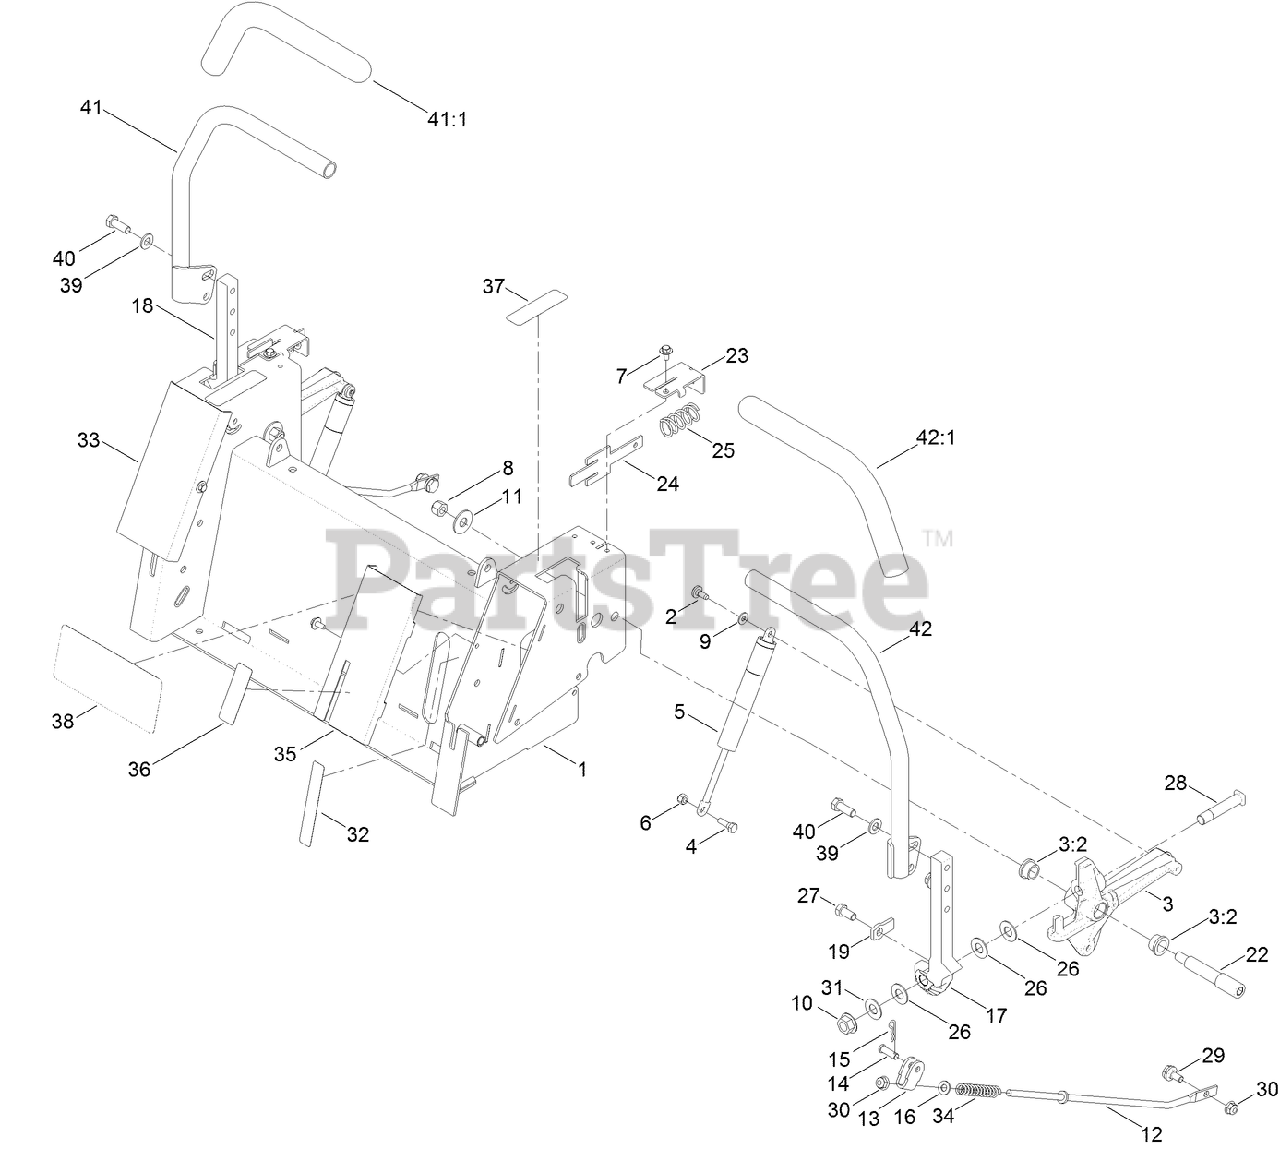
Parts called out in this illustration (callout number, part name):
1	BOX-CONTROL
2	SCREW-SHOULDER
3	ACTIVATOR ARM ASM
3:2	BUSHING
4	BOLT-SHOULDER
5	DAMPER
6	NUT-LOCK, NI
7	SCREW-HHFTF
8	NUT-LOCK, NI
9	WASHER
10	NUT-HF
11	WASHER-FLAT
12	ROD-CONTROL
13	BRACKET-CONTROL
14	PIN-CLEVIS
15	PIN-COTTER
16	WASHER-PLAIN
17	ARM-ACTUATOR, LH
18	ARM-ACTUATOR, RH
19	TAB-STOP
22	BOLT-SHOULDER
23	BRACKET-RETURN
24	PLATE-RETURN
25	SPRING-COMPRESSION
26	WASHER-PIVOT
27	SCREW-HH
28	BOLT-SHOULDER
29	BOLT-SHOULDER,HFH
30	NUT-HF, NI
31	WASHER-TEFLON
32	DECAL-FILL, FUEL
33	COVER-CONTROL, RH
34	SPRING-RETURN, NEUTRAL
35	COVER-CONTROL, LH
36	DECAL-BRAKE, PARKING
37	DECAL-CONTROL, MOTION
39	WASHER-FLAT
40	SCREW-HH
41	HANDLE-CONTROL, RH
42	HANDLE-CONTROL, LH
